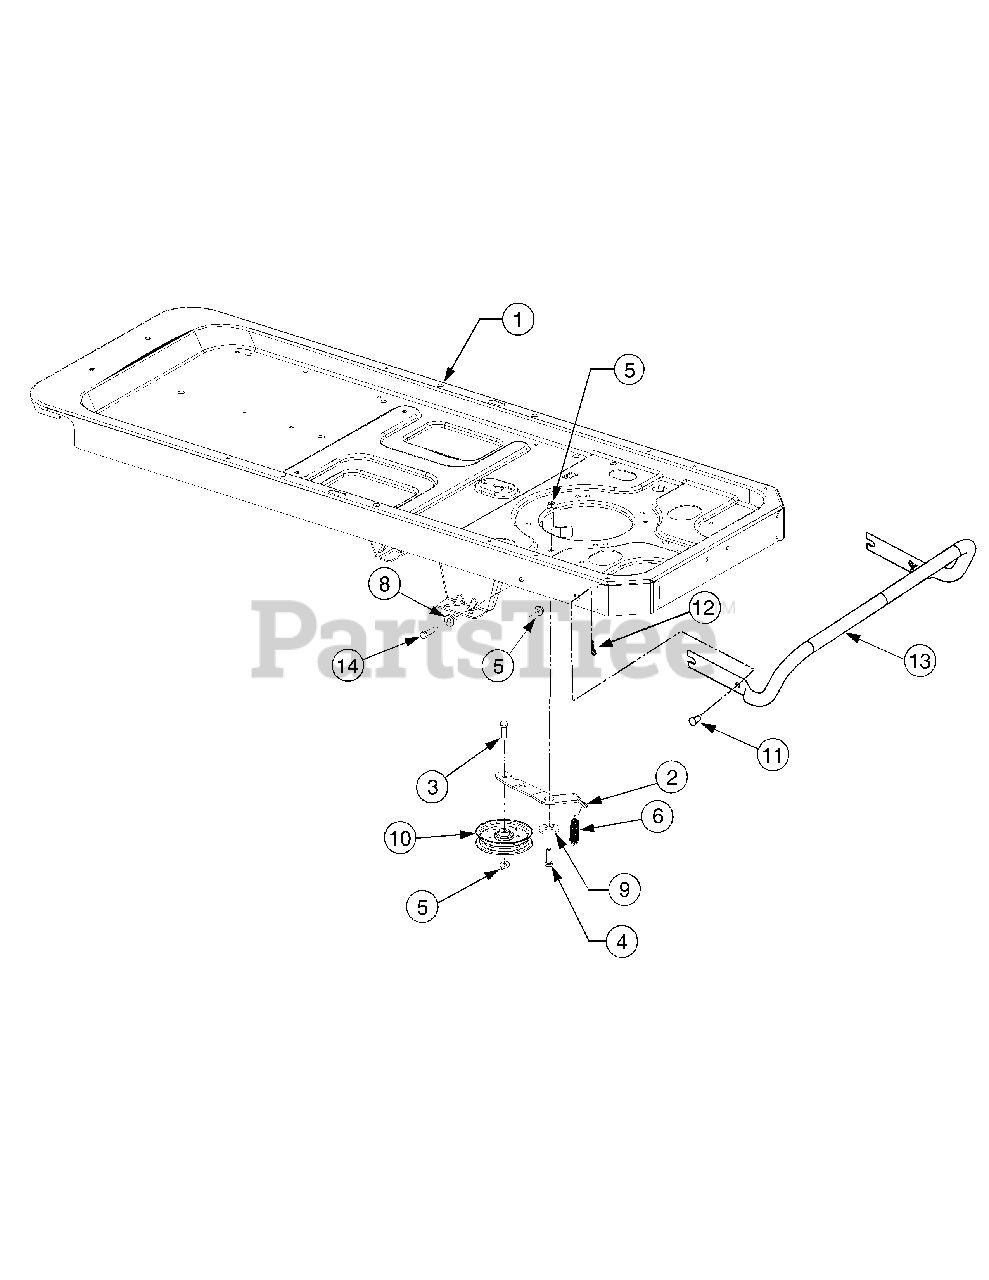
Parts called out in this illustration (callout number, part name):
3	Hex Screw 3/8-16 x 1.50
4	Hex Bolt 3/8-16 x 1.25
5	Flange Lock-Nut 3/8-16 Gr. F Nylon
6	Ext. Spring 5.06" Lg.
8	Shoulder Spacer .38 x 1.0 x .70
9	Shoulder Spacer .884 x .190
10	Idler Pulley w/Flange 4.25 Dia
11	Clevis Pin .50 x .78" Lg.
12	Cotter Pin .080 x 1.56
